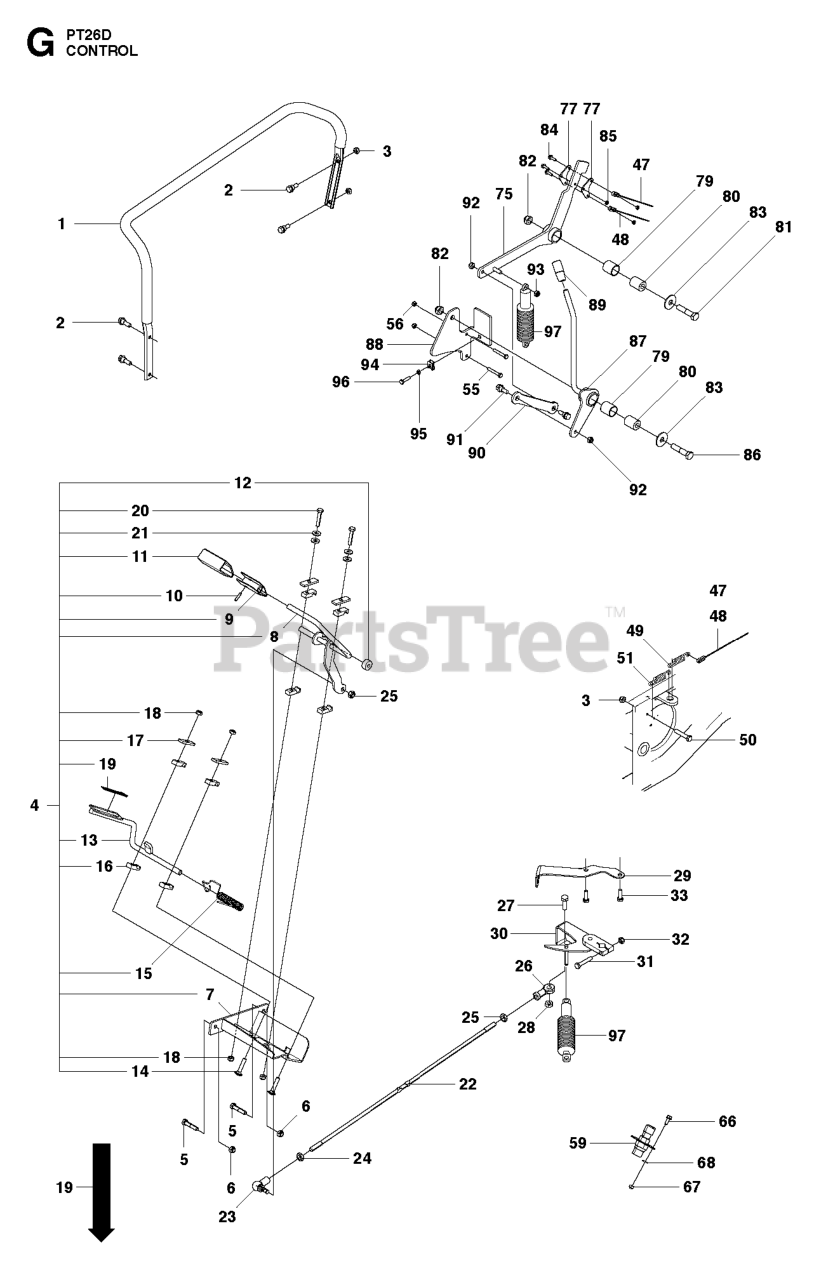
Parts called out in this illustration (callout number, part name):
1	HANDLE ASSY
3	LOCKNUT M8
6	LOCKNUT M8
11	PEDAL RUBBER
14	Screw Mvbf 8 X 40
18	NUT
21	WASHER BRB 8.4X17
25	NUT
28	NUT
31	SCREW
32	LOCKNUT M8
33	SCREW M6S 8X25
50	SCREW
56	LOCKNUT M6
66	Screw
67	LOCKNUT M6
68	WASHER
79	BUSHING
84	SCREW M6S 5X20
85	LOCKNUT M5
92	LOCKNUT M8
97	SHOCK ABSORBER
